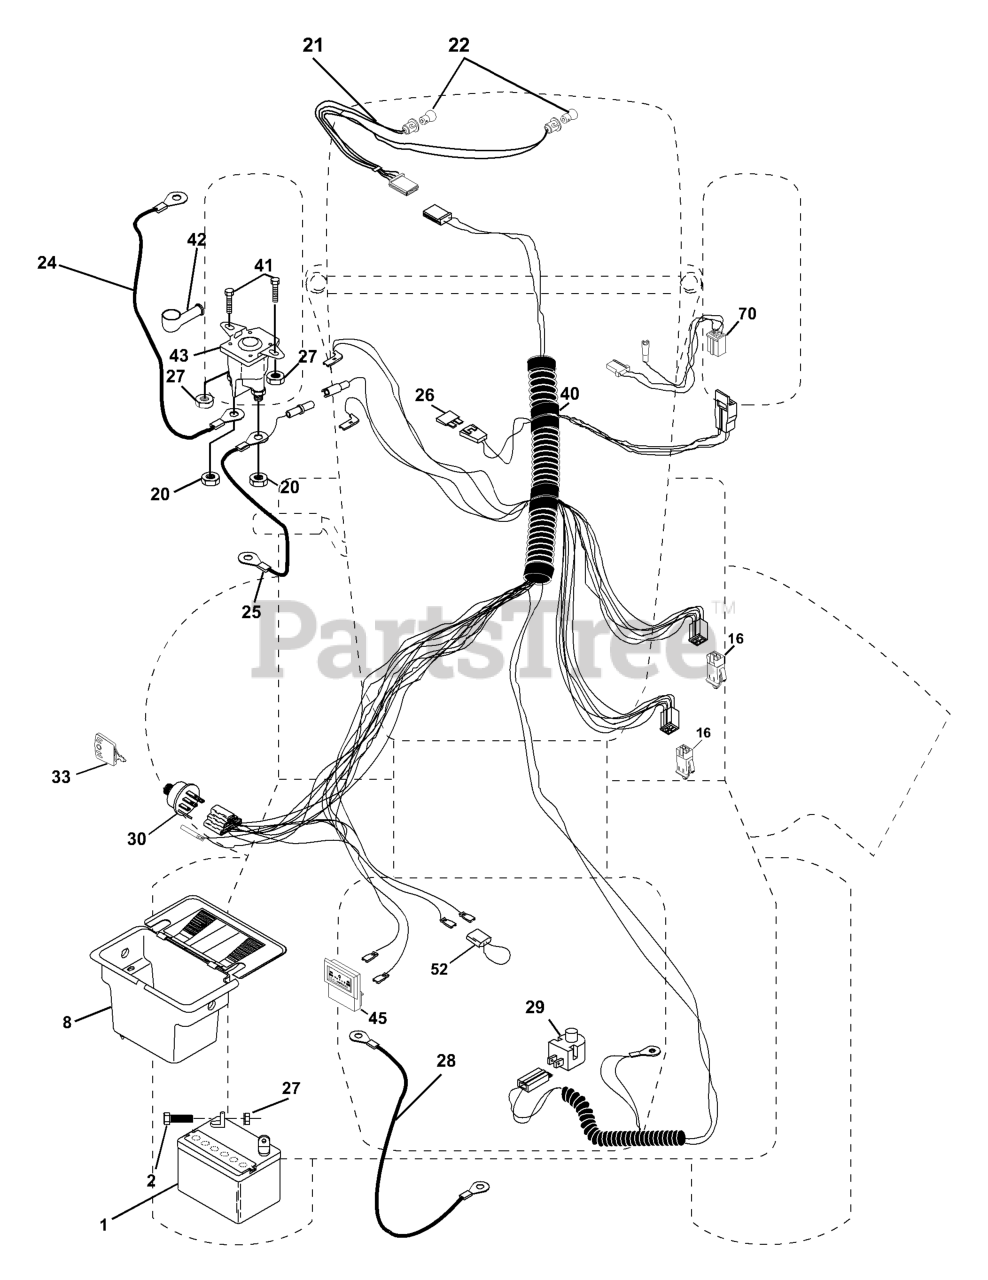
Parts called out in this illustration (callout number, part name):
1	BATTERY 12 VOLT 25 AMP
2	BOLT.HEX.1/4.X.3/4.DICHROMATE
8	CASE BATTERY MECH HINGE
16	SWITCH INTERLOCK
20	NUT
24	BATTERY CABLE GT
25	CABLE BATTERY
26	FUSE 15 AMP
27	NUT
28	CABLE T
29	RP.SWITCH.PLUNGER.NC.GRAY
30	SWITCH IGN
33	KEY MLD GEN DELTA
40	HARNESS, IGN. LTH120
41	BOLT
42	TERMINAL COVER
43	SOLINOID
45	AMMETER
52	WIRE PROTECTION LOOP
70	ENGINE HARNESS
